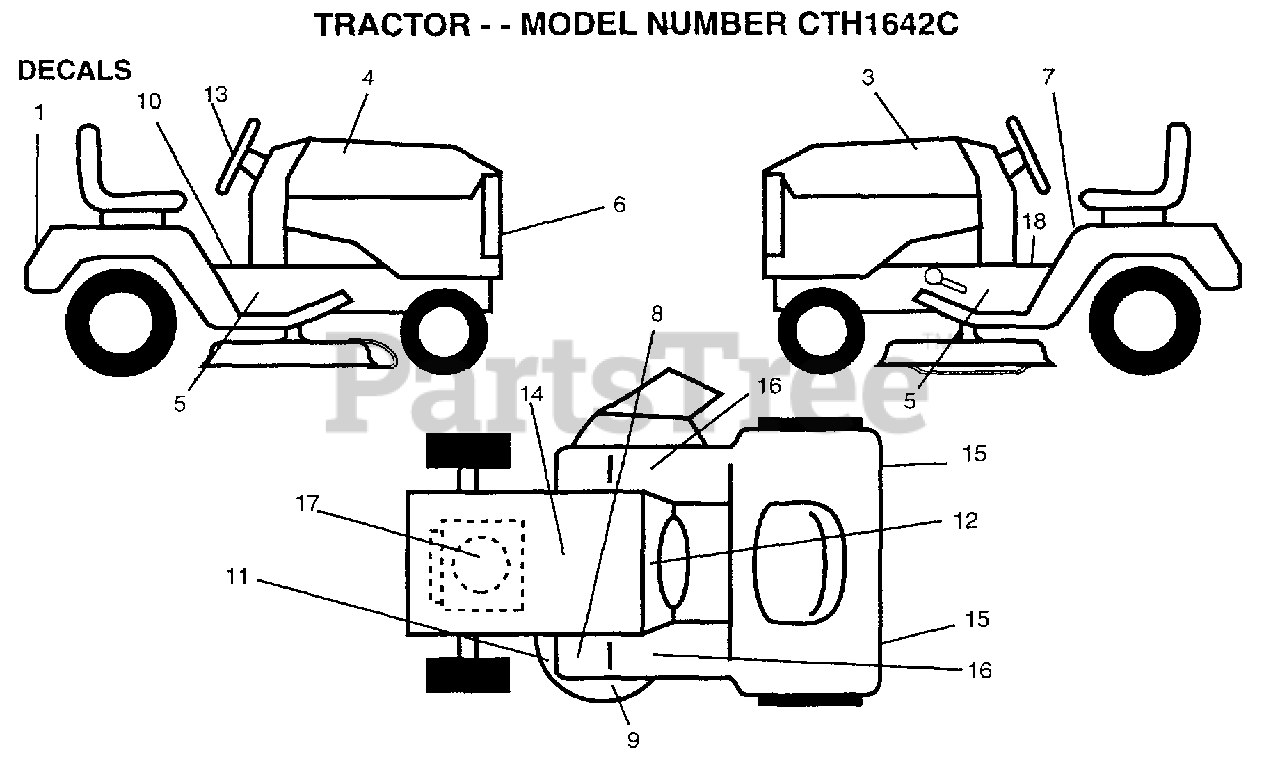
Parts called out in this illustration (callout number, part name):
1	DECAL.FEND.RALLY
3	DECAL HOOD LH
4	DECAL.HOOD.RH
5	DECAL.CHAS.42.HYD
6	DECAL.GRILLE.RLY
7	DECAL
10	DECAL BRAK PARK
11	DECAL
12	DECAL.DASH.INST.
13	DECAL.WHL.STR.RLY
14	DECAL.BTRY.DANGER
15	REFLECTOR-TAIL YT
16	FOOTREST PAD
17	DECAL, HP ENGINE
18	DECAL SADLE HYDRO
